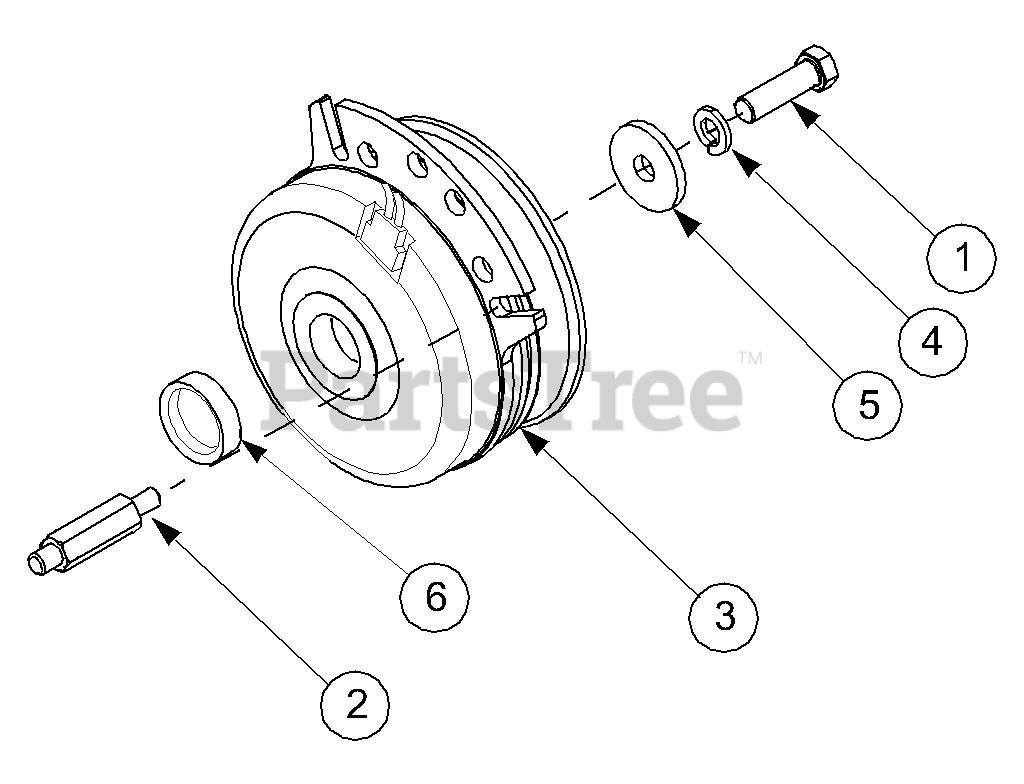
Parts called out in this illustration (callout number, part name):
1	Screw, Hex Cap, 7/16-20 x 1.5 GR5
2	Stud, Clutch Stop
3	Clutch Assy, PTO
4	Washer, Lock, 3/8
5	Washer, Flat, .445 x 1.5 x 1.72 Hdn
